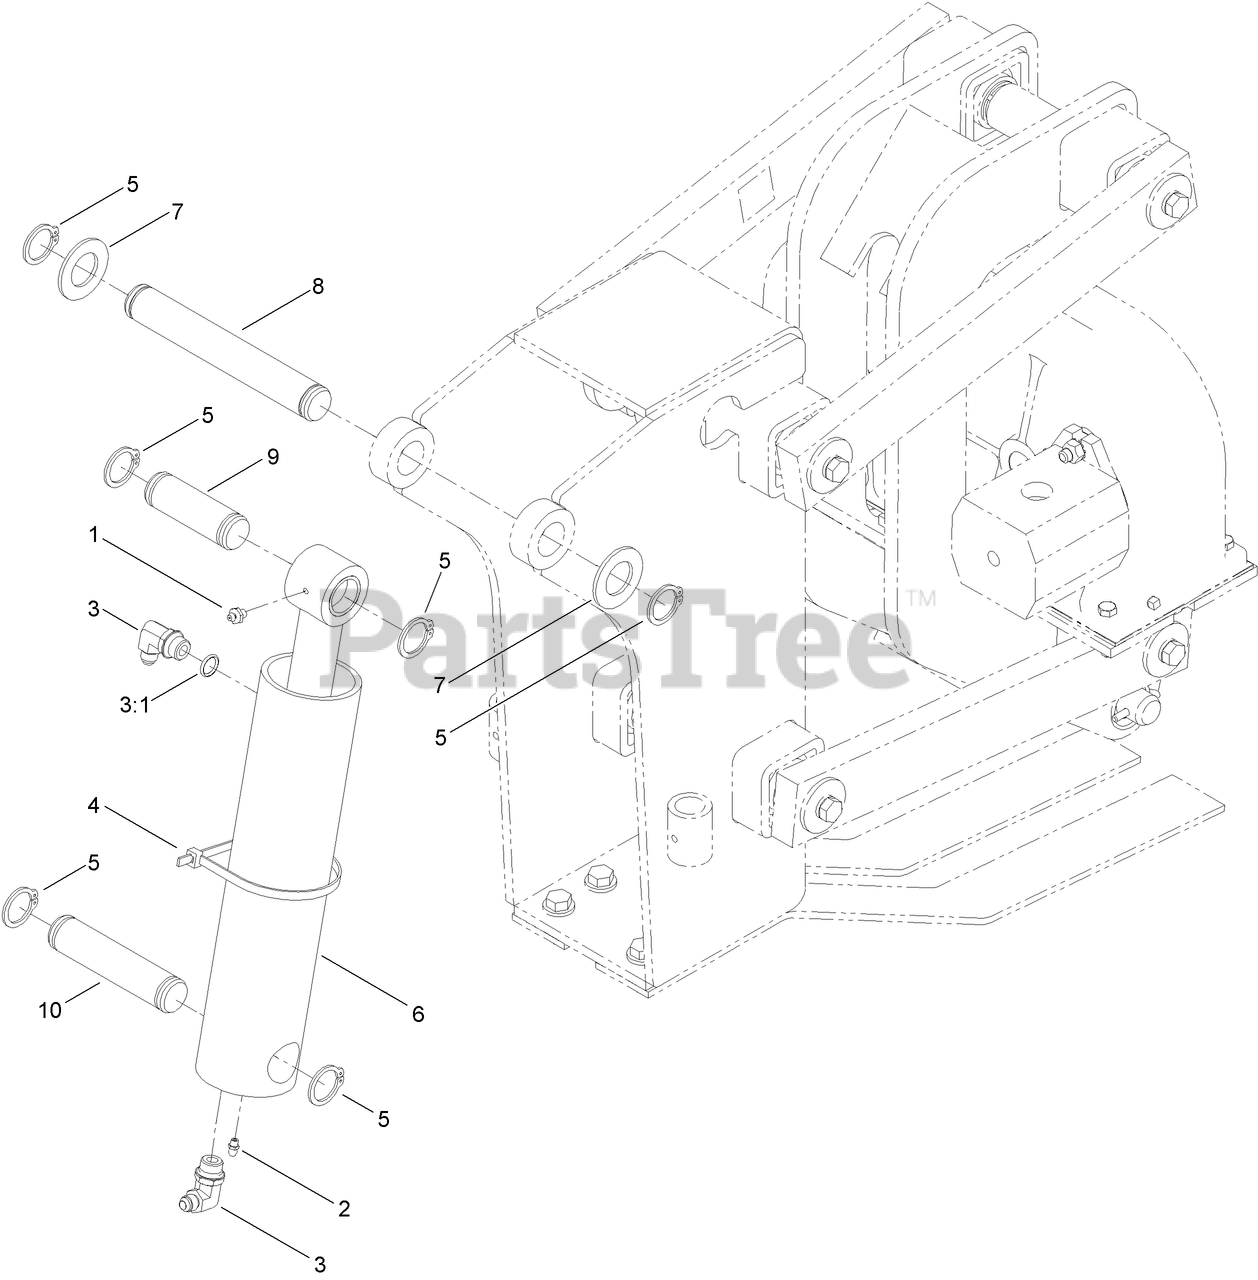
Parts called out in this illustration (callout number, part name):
1	FITTING-GREASE
2	FITTING-GREASE
3	FITTING-ELBOW, 90 DEG
3:1	O-RING
4	TIE-CABLE
5	RING-RETAINING, EXTERNAL
6	HYD CYLINDER ASM
7	WASHER-10 GAUGE
8	PIN-LIFT
9	PIN-CLEVIS
10	PIN-CLEVIS
